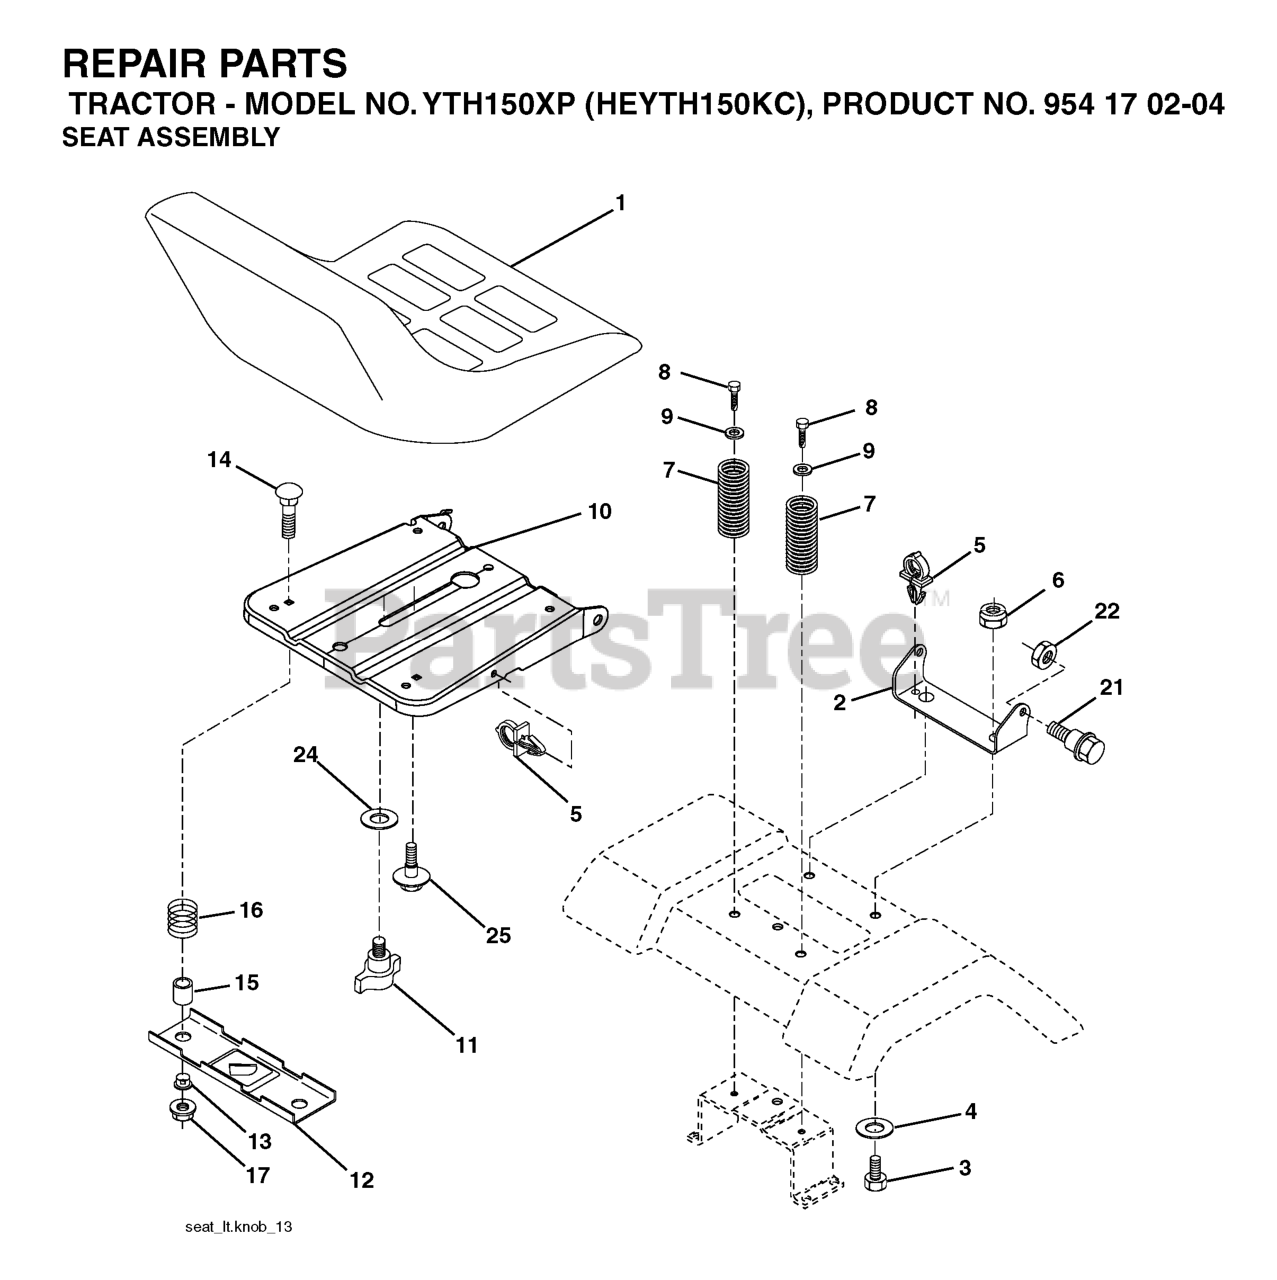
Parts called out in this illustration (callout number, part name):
1	Battery 12 Volt 25 Amp
2	BOLT.HEX.1/4.X.3/4.DICHROMATE
8	BOX.BATTERY.MOUNT.FRONT.LT
16	SWITCH INTERLOOK PUSH-IN
21	HARNESS ASSY LIGHT
24	CABLE.BATT.POS.WIRE.TG.DA SOL
25	CABLE.START.RED.17.5".
26	FUSE 20AMP
27	NUT
28	CABLE GROUND 6 GA 21" 90T BLK
29	SWITCH.SEAT.DELTA.OPC.
30	SWITCH.IGN.DELTA.W.LGH.ROS
33	KEY MLD GEN DELTA
40	HARNESS.IGN.DASH.HUQ/P
41	SCREW
42	TERMINAL COVER
43	SOLENOID.W/BRASS.PLUNGER
46	GAUGE.SERVICEMINDER.HR
50	RP.PTO.SWITCH.8 TERMINAL.BLACK
55	SCREW.THDROL.5/16-18X3/4.TTY
71	HARNESS-CHASSIS SUB
90	COVER.TERMINAL.BATTERY
91	STRAP.BATTERY.MOUNT.FRONT(2 2)
99	SCREW HEXWSHR 1/4-20X3/4
